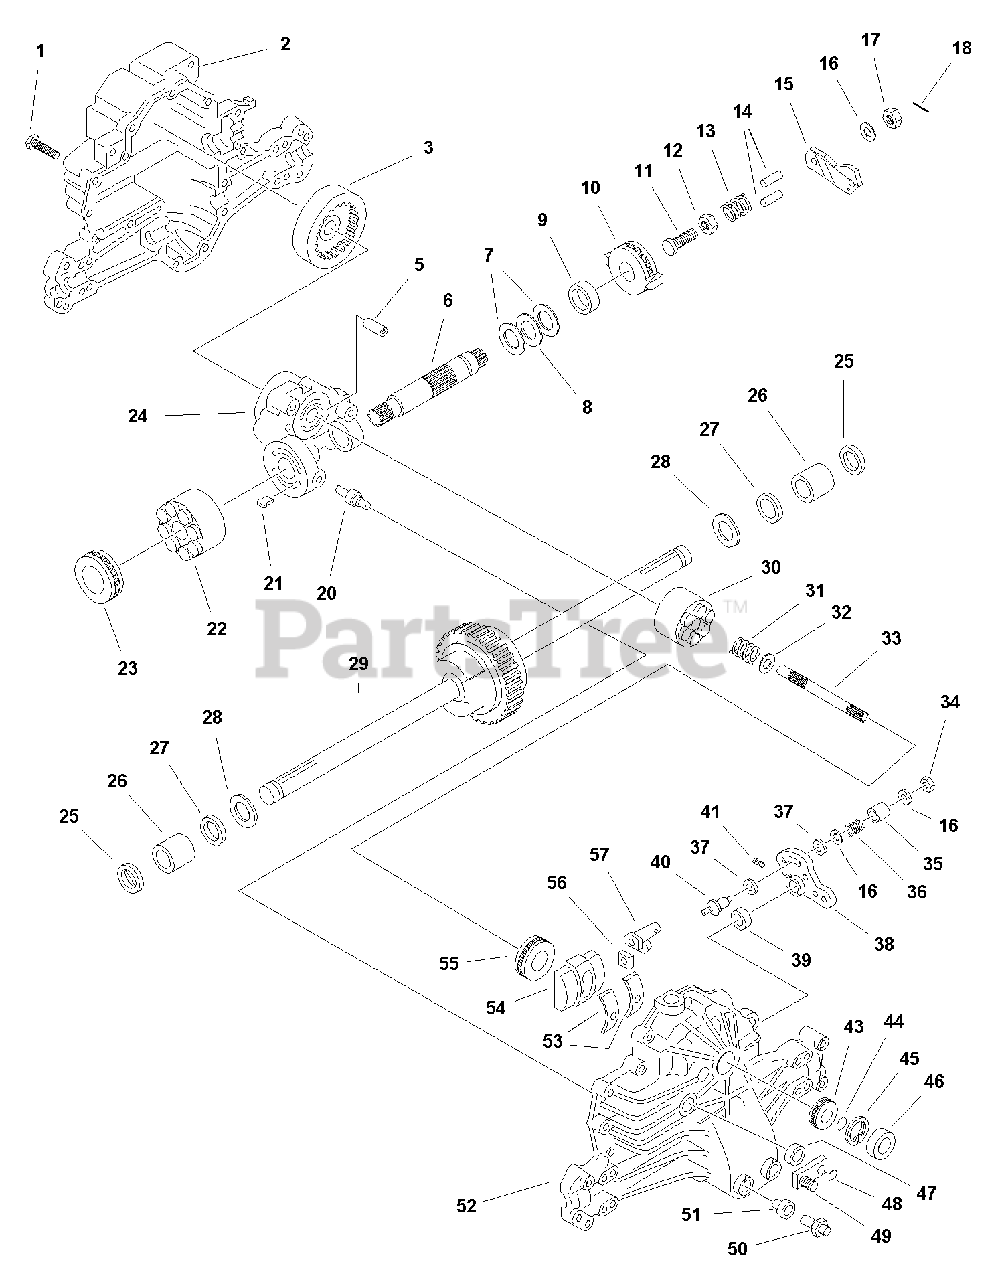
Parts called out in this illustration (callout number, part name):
1	BOLT, 1/4-20 x 1-3/8
2	HOUSING, Lower
3	OIL FILTER ELEMENT
6	SHAFT, Motor
8	RING, Retaining
9	SEAL, Lip .26 x .42 x .8
10	BRAKE ROTOR/STATOR KIT
11	BOLT, 5/16-18 x 1-3/4
12	NUT, Hex, Lock, 5/16-24
13	COMPRESSION SPRING
14	PIN, Actuating
15	ARM, Actuating
16	WASHER, 7/16 x 7/8 x 1/16
17	CASTLE NUT, 5/16-24
18	COTTER PIN
20	ACTUATOR, Bypass
21	BYPASS PLATE
22	BLOCK, Cylinder (Motor) Assembly
23	BEARING, Thrust .42 x .68 x .16
24	CENTER SECTION ASSEMBLY
25	SEAL, Wiper
26	SLEEVE BEARING
27	SEAL, 3/4 x 1-1/4 x 1/4
28	WASHER, 3/4 x 1.5 x .13
29	DIFFERENTIAL ASSEMBLY
30	BLOCK, Cylinder Pump Assembly
31	SPRING, Block
32	WASHER, Block Thrust
33	SHAFT, Input
34	NUT, Hex Lock, 5/16-24
37	PUCK, Dampener
38	ARM, Control
40	STUD, 5/16-24
43	BEARING, Shaft Ball
44	RING, Wire, Retaining
45	RING, Retaining
47	SEAL, Lip, 1.0 x .25 x .7
48	RING, Retaining
49	ARM, Bypass
50	BREATHER ASSEMBLY
51	BUSHING, Vent
52	UPPER HOUSING ASSEMBLY
53	BEARING, Cradle
54	SWASHPLATE, Variable
55	BEARING, Thrust .30 x .52 x .13
56	GUIDE, Slot
57	ARM, Trunnion
